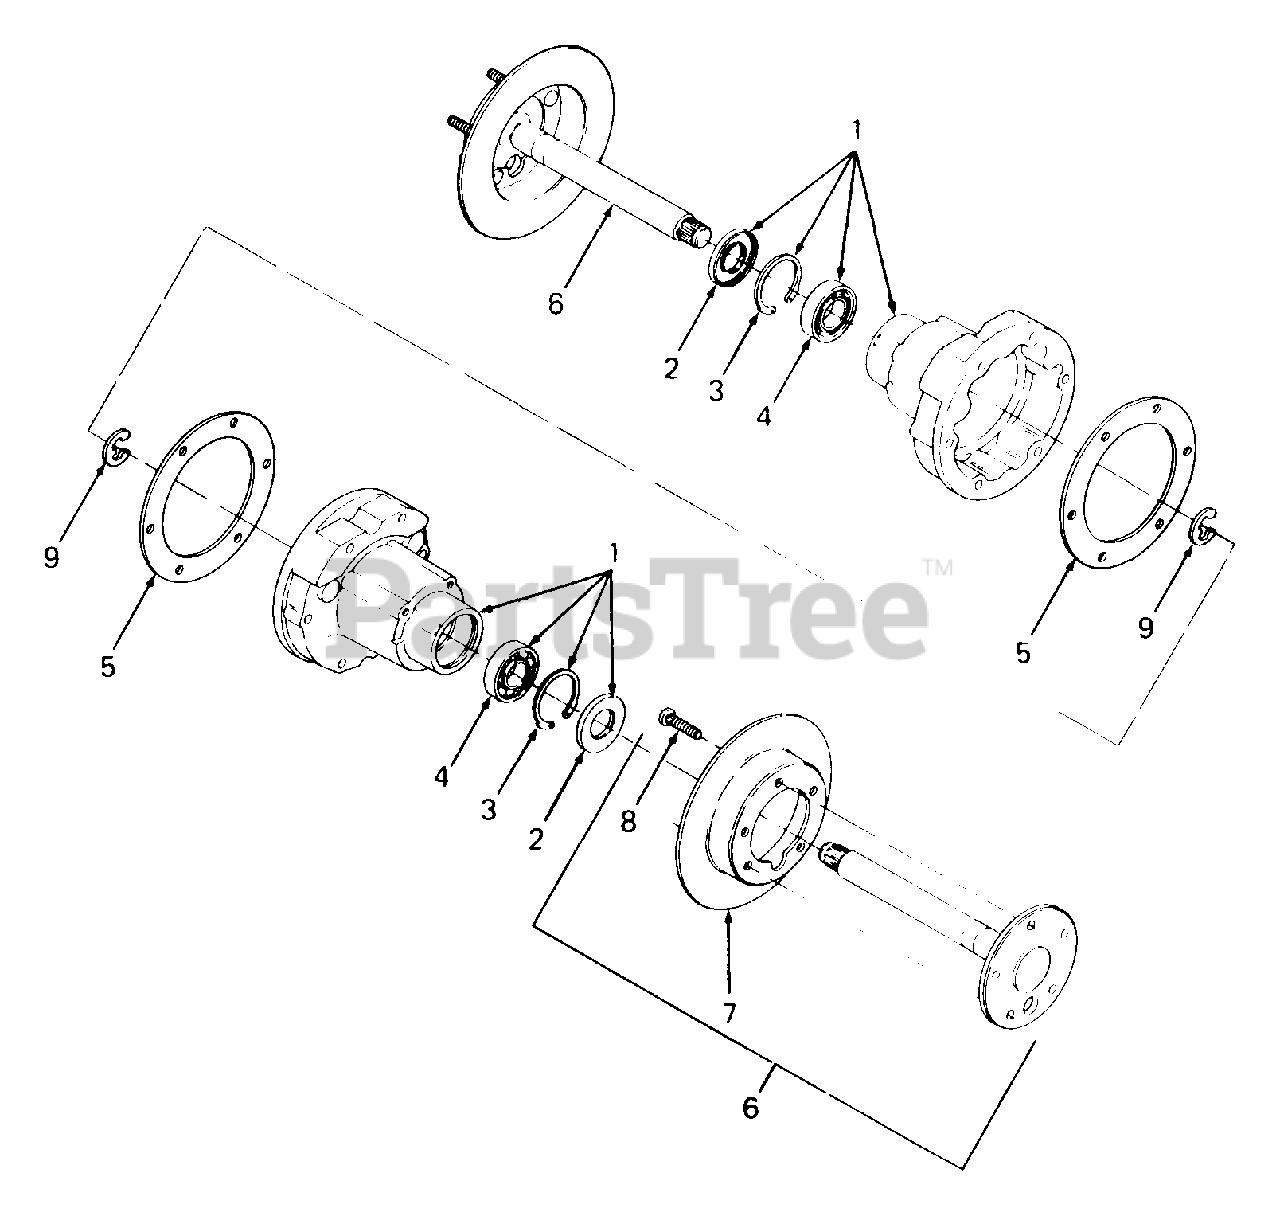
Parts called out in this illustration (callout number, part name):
1	Carrier Assy, Rear Axle
2	Seal, Oil
3	Ring, Retaining
4	Bearing, Ball
5	Gasket, Carrier
6	Axle Assy, Rear
7	Disc, Brake
8	Bolt, Lug
9	Retainer, E-Ring
